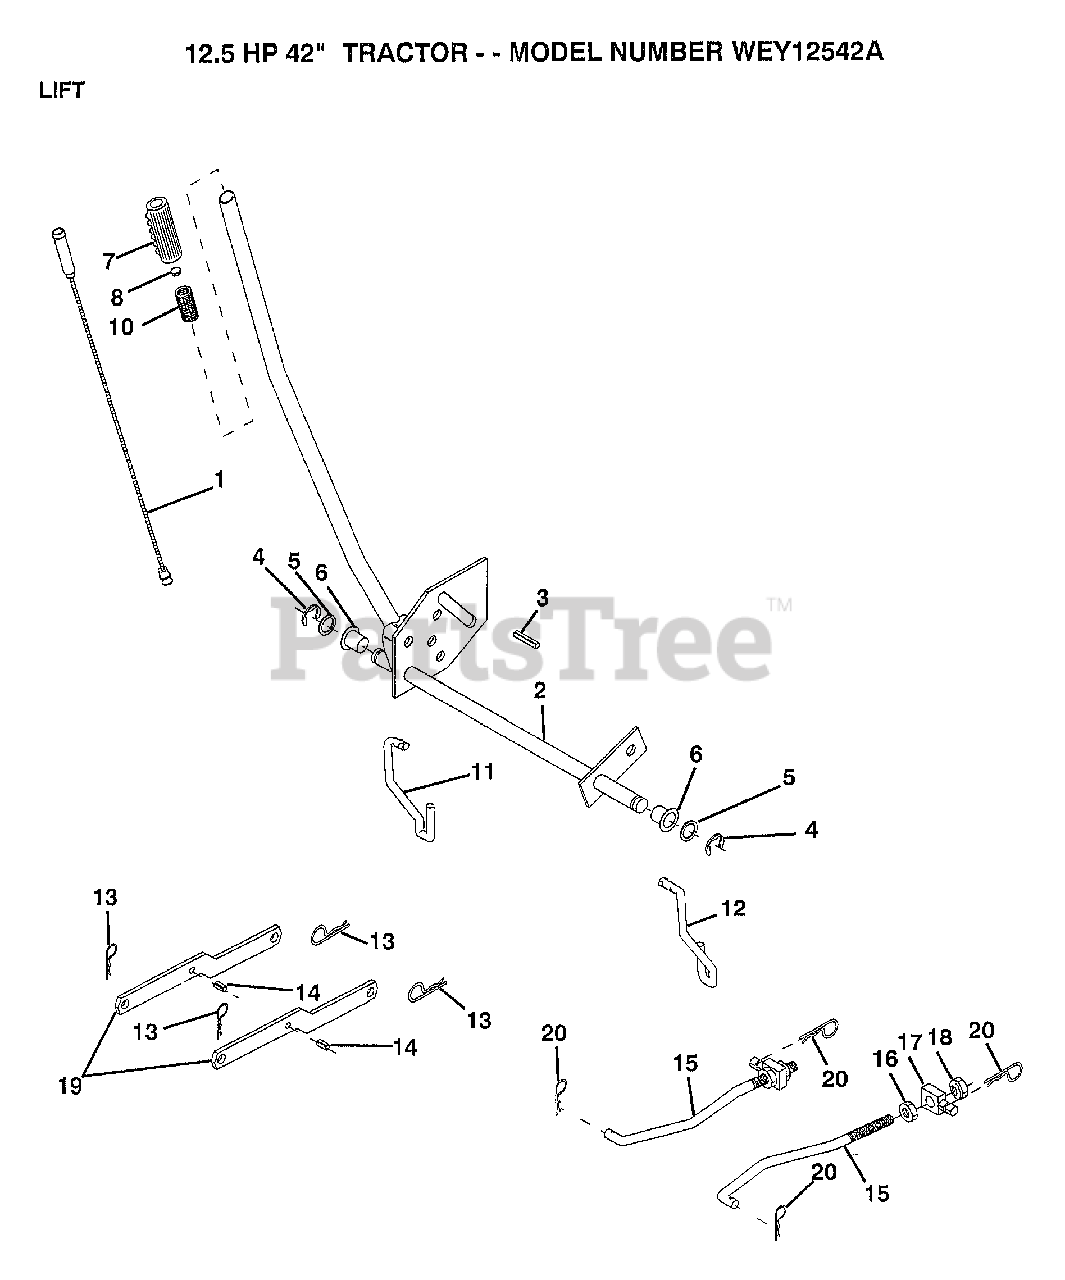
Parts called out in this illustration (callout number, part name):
1	WIRE ASM
2	SHAFT.ASM.LIFT LH
3	PIN-GROOVE LT
5	WASHER
6	NYLON BEARING
7	GRIP
11	LINK LIFT LH
12	LIFT LINK RH
14	"PIN,SPRING"
15	LINK.FRONT
16	NUT
17	TRUNION
18	NUT.LK.W/WSH.1/2.
20	RETAINER.SPRING
